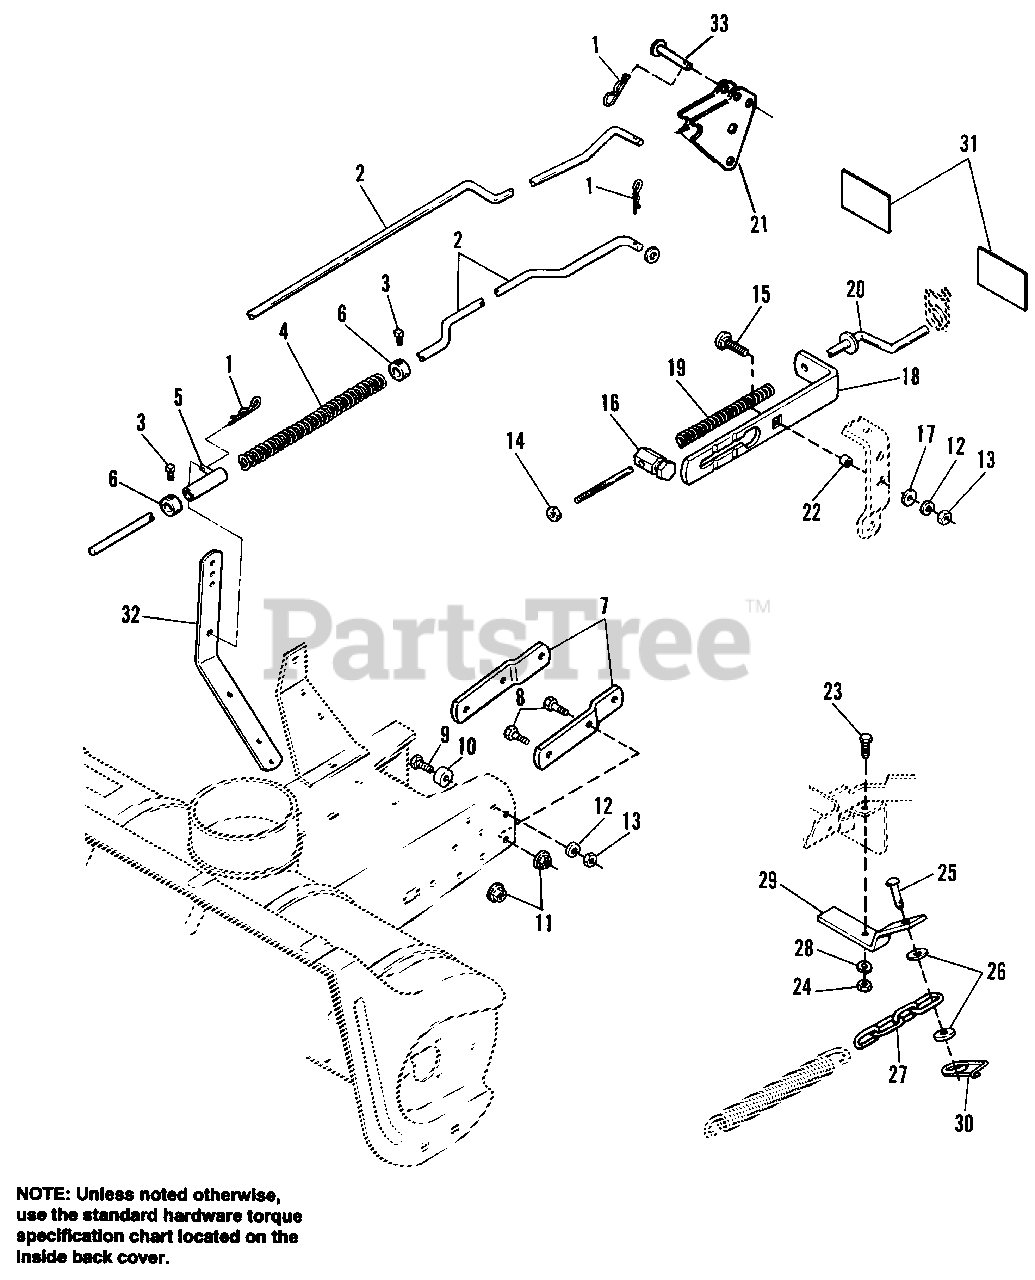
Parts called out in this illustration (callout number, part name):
1	CLIP, Spring
2	ROD, Lift (Manual Lift Only)
2	ROD, Lift (Electric Lift Only)
3	SETSCREW, 5/16 x 1/2
5	GUIDE ASSY., Rod
6	COLLAR, Set
7	CLIP, Frame
8	CAPSCREW, Hex, 7/16 x 1
9	CAPSCREW, Hex, 3/8-16 x 1-1/4 (Manual Lift Only)
10	SPACER (Manual Lift Only)
11	LOCKNUT, Hex, Flange, 7/16-14
12	LOCKWASHER (Manual Lift Only)
13	NUT, Hex, Full, 3/8-16 (Manual Lift Only)
14	LOCKNUT, Hex, Full, 3/8-16
15	CARRIAGE BOLT, 3/8-16 x 1-1/4
17	WASHER, Plain, 5/16
18	GUIDE, Spring
20	ROD ASSY., Adjustment
21	LIFT ARM ASSY. (Incl. Ref. No. 33 and Qty. 1 Ref. No. 1)
23	CAPSCREW, Hex, 5/16-18 x 1
24	NUT, Hex, Full, 5/16-18
25	PIN, Hitch
26	WASHER, Plain
27	CHAIN, 4-Link
28	LOCKWASHER, 5/16
29	BRACKET, Spring Anchor
30	CLIP, Spring
32	ARM, Support
33	PIN, Round Hd., Drilled, 1/2 x 2-1/2
